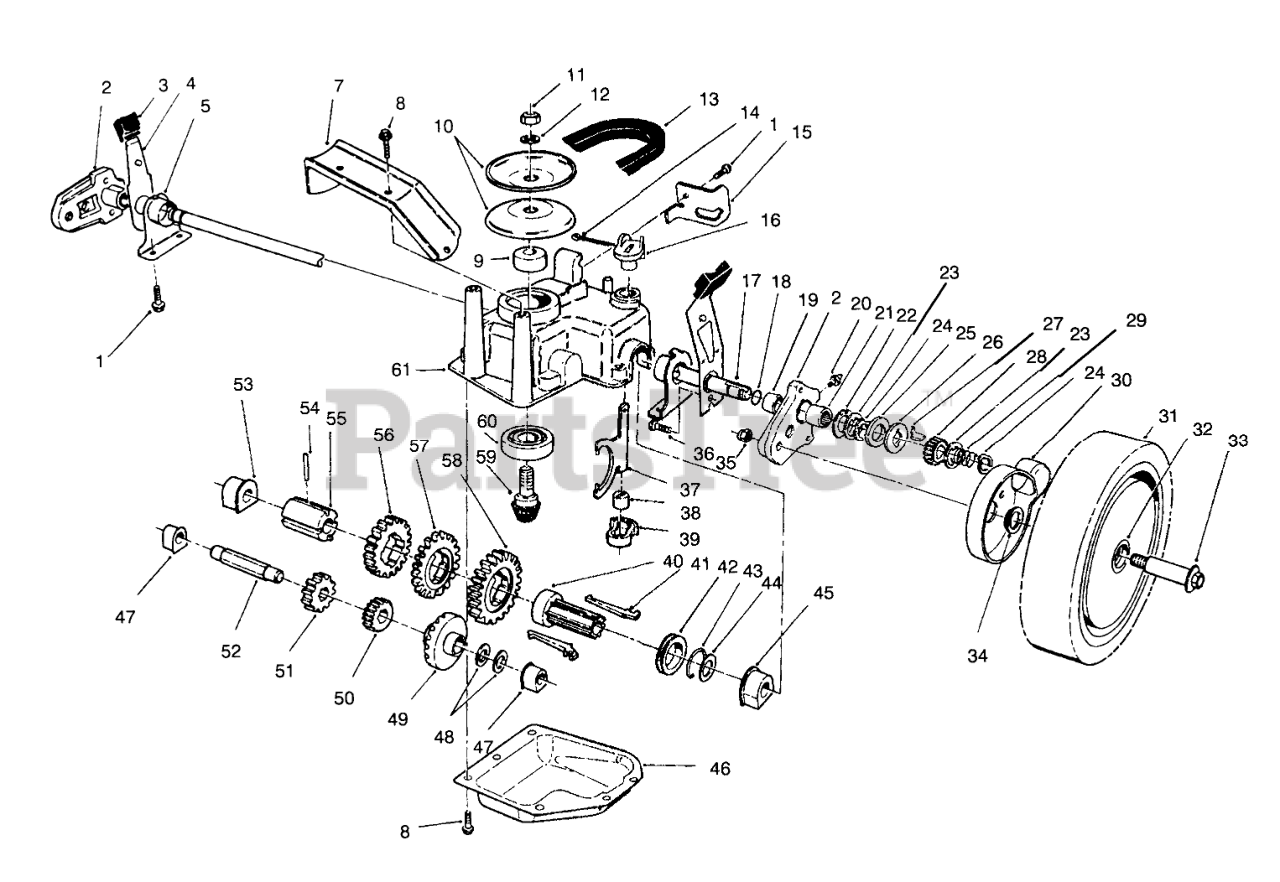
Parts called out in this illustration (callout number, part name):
1	SCREW-HWHTF
2	Pivot Arm Assembly (Incl. Ref. #19-21)
3	KNOB-ARM
4	SPRING ARM ASM
5	CAP-END
7	Bracket-BeltGuide
8	SCREW-HWHTF
9	SPACER
10	Pulley Half
11	NUT-HEX
12	WASHER-FLAT
13	V-BELT
14	PIN-COTTER
15	RETAINER-CABLE
16	LEVER-SHIFT
17	SHAFT-OUTPUT
18	O-RING
19	BUSHING
20	FITTING-GREASE
21	BEARING-ROLLER
22	WASHER-ARM, PIVOT
23	WASHER-THRUST, KEYED
24	RING-CLIP, LOCKING
25	RING-FRICTION
26	WASHER-CLUTCH
27	KEY-ROCKING, LH
28	GEAR-PINION
29	SPRING-COMPRESSION
30	COVER-WHEEL
31	Wheel Tire & Gear Assy. (Incl. Ref. #32)
32	BUSHING
33	WHEEL BOLT
34	SPACER-COVER, WHEEL
35	NUT-LOCK
36	SCREW-HSH, THREAD FORMING
37	YOKE-SHIFT
38	BUSHING-YOKE
39	RETAINER-FORK, SHIFT
40	SLEEVE-KEY, SHIFT
41	KEY-SHIFT
42	COLLAR-SHIFT
43	CLIP-SPRING
44	WASHER-PLAIN
45	BUSHING-OUTPUT
46	Cover-Gearcase
47	BUSHING
48	WASHER-THRUST
49	Gear-Bevel
50	PINION-20T
51	PINION-25T
52	SHAFT-INTERMEDIATE
53	BUSHING
54	PIN-SPRING
55	SLEEVE-GEAR
56	GEAR-39T
57	GEAR-44T
58	GEAR-49T
59	Gear-Pinion
60	BEARING-BALL
61	CASE-GEAR, UPPER
